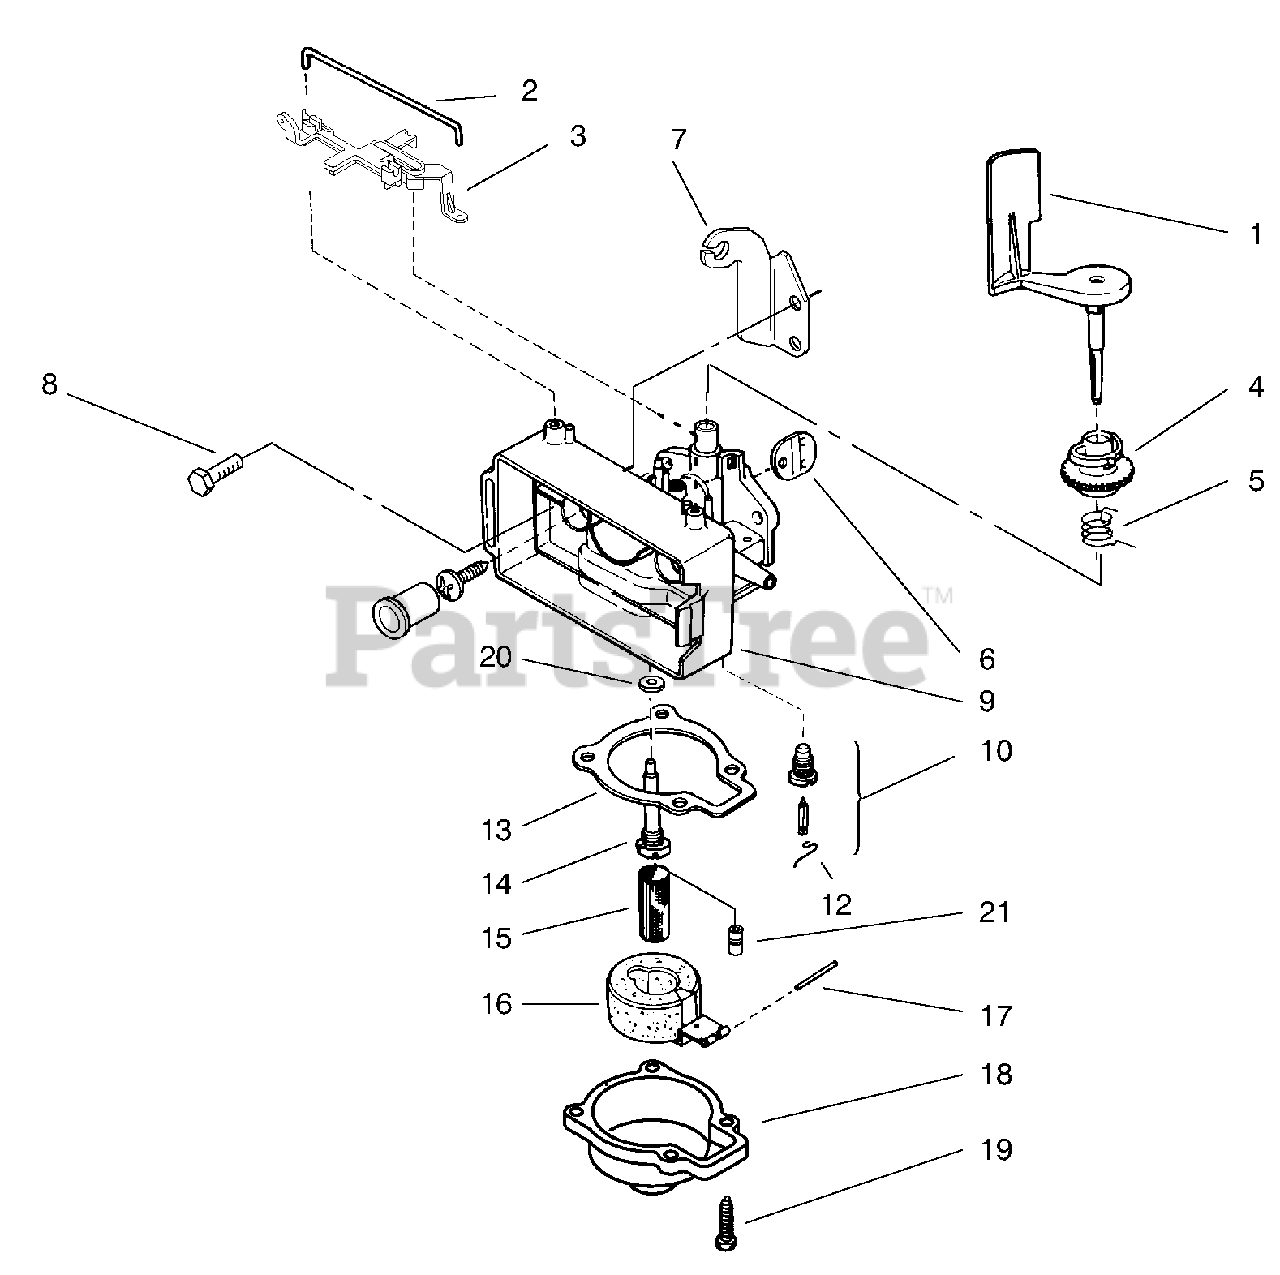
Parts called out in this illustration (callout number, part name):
1	Air Vane&shaft
2	RETAINER
3	LEVER-ADJ. VF
4	COLLAR-ADJUST, AIRVANE
5	SPRING-GOV V
6	DISC-THRO. V
7	BRKT-THRO.CONT V
8	SCREW V
9	CARB. BODY V
10	Kit-Float Valve, Body & Seat (Incl. Ref. #12)
14	NOZZLE VF
15	FILTER-FUEL VS
16	FLOAT & ARM ASM
17	PIN-STRAIGHT
18	CHAMBER-FLOAT
19	SCREW-HH
21	JET-MAIN VF
